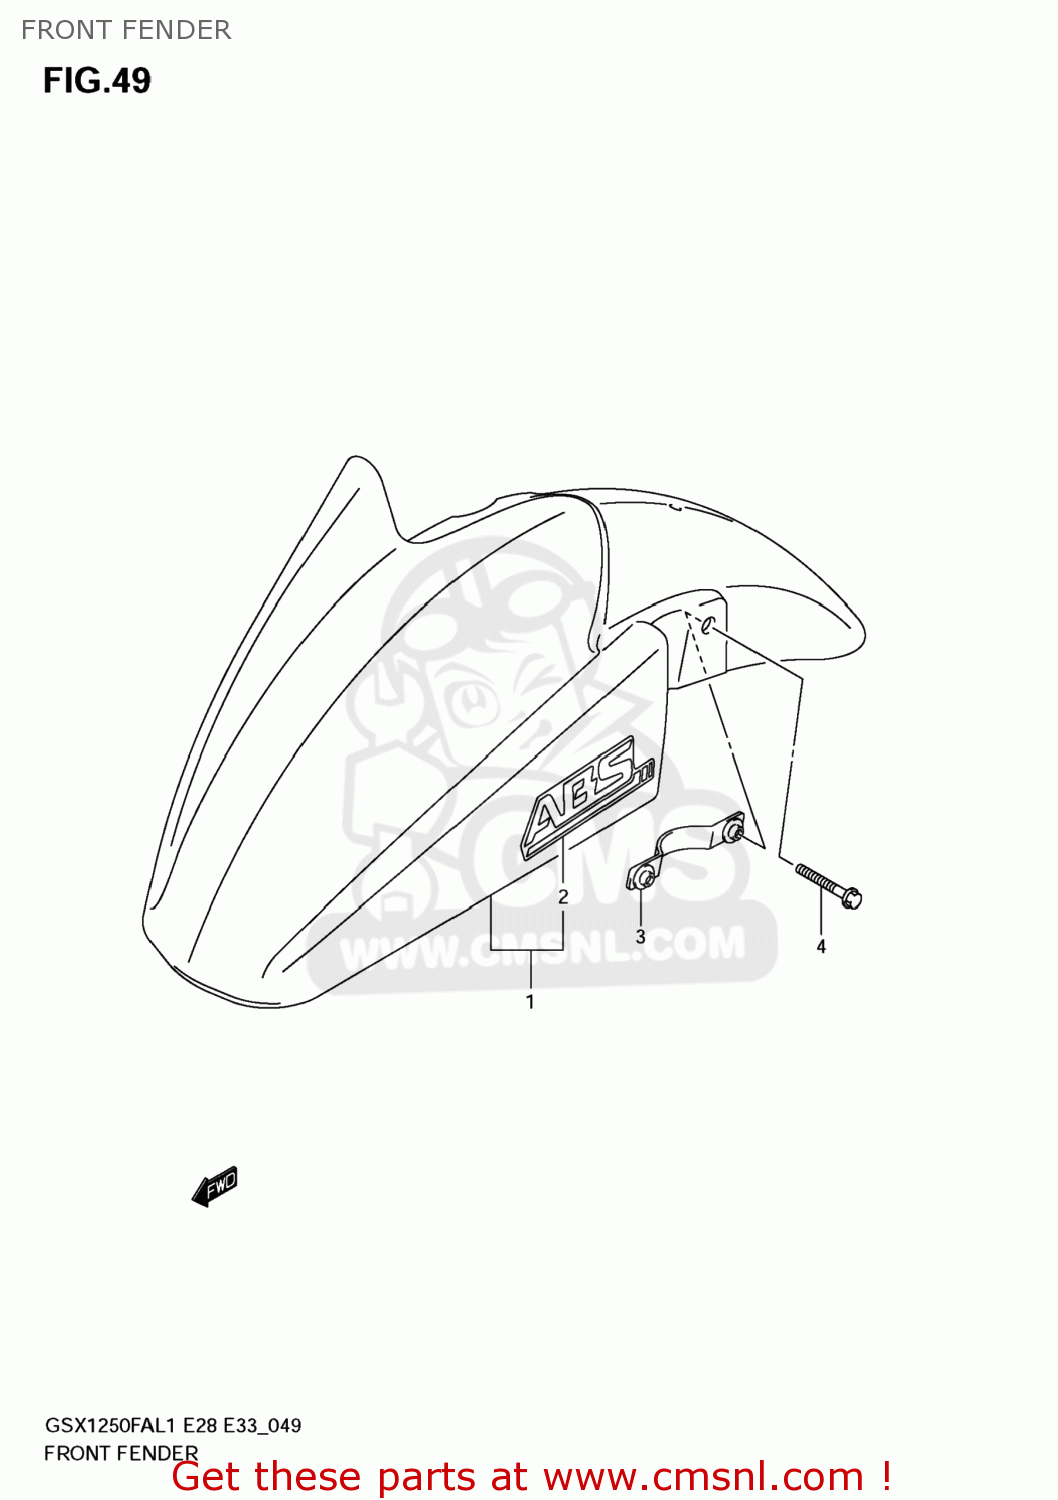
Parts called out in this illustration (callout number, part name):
1	FENDER,FR
2	EMBLEM,ABS
3	PLATE,FR FENDER
4	BOLT(6X35)
